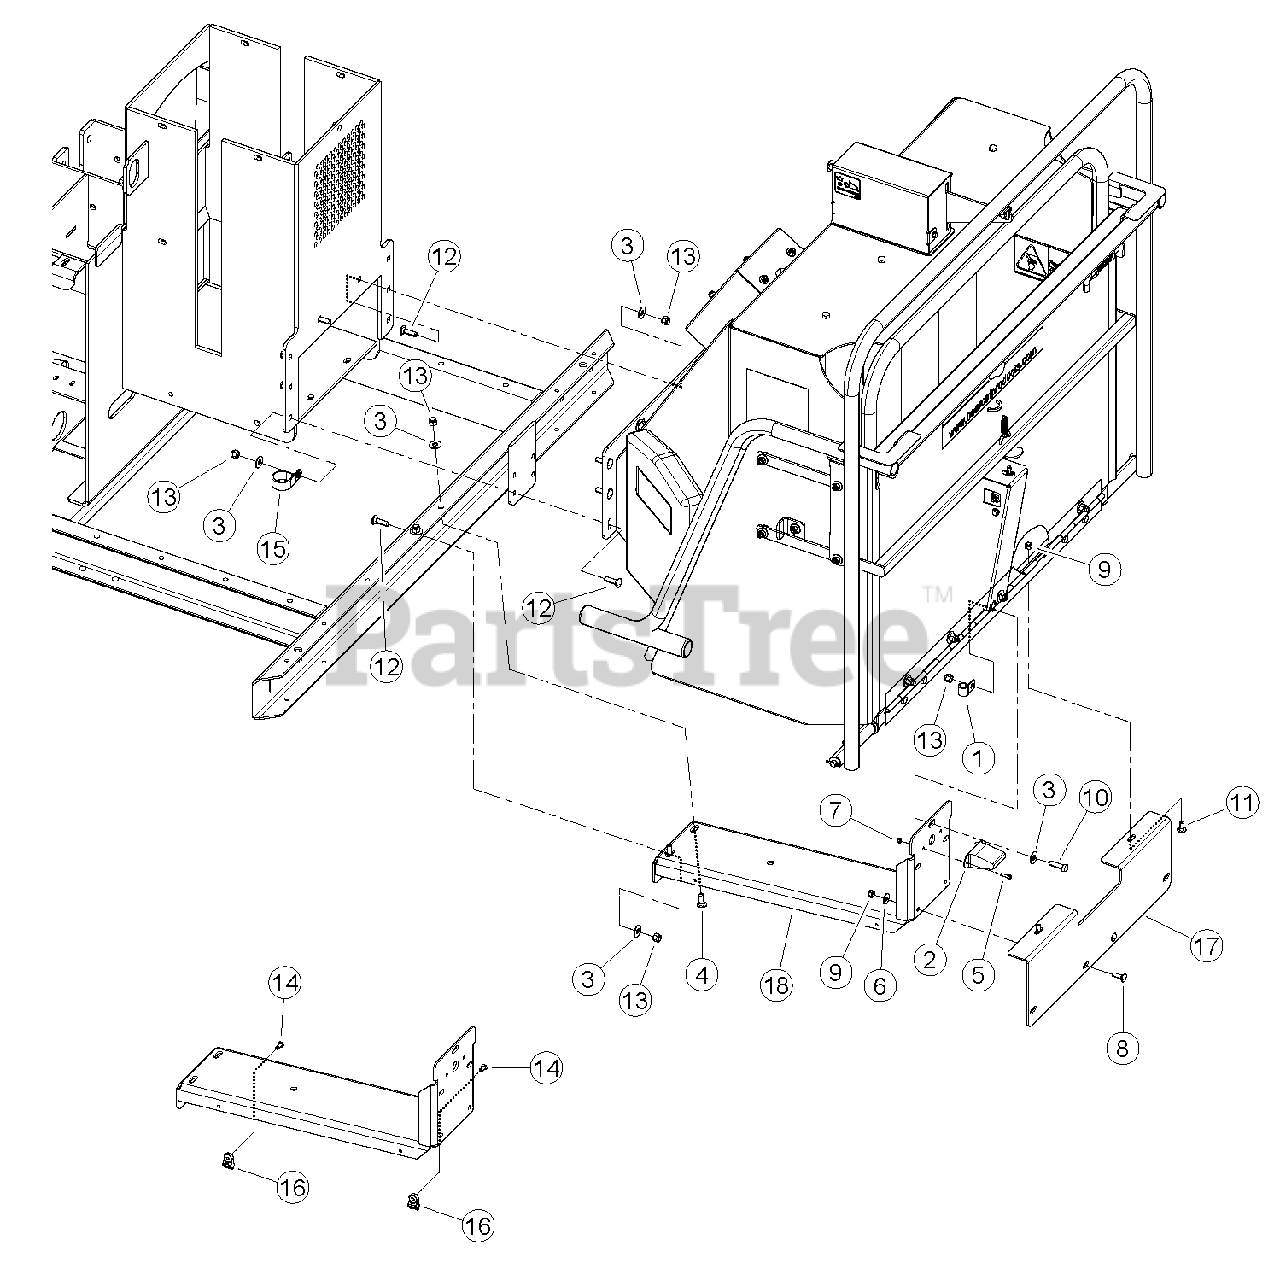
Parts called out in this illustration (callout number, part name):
1	CLAMP, 9/16" COATED
2	LIGHT, LICENSE PLATE
3	WASHER, 3/8 FLAT ZP
4	BOLT, 3/8 X 1 CRG GR5 NC ZP
5	SCREW, #10 X 3/4 HEX TAP SC
6	WASHER, 5/16 FLAT ZP
7	NUT, 8-32 NYLOCK
8	BOLT, 5/16 X 1 CRG GR5 ZP
9	NUT, 5/16 NE NYLOCK ZP
10	BOLT, 3/8 X 1-1/4 HEX HD GR5 ZP
11	BOLT, 5/16 X 3/4 CRG GR5 NC ZP
12	BOLT, 3/8 X 1-1/4 CRG GR5 NC ZP
13	NUT, 3/8 NE NYLOCK ZP
14	RIVET, AL BLIND 1/4 X 3/4 DOME HEAD
15	CLAMP, 1-9/16" COATED METAL
16	CLAMP, CABLE MOUNT
17	BRACKET, EUROPEAN LICENSE
18	SUPPORT, CHUTE/SPARE
